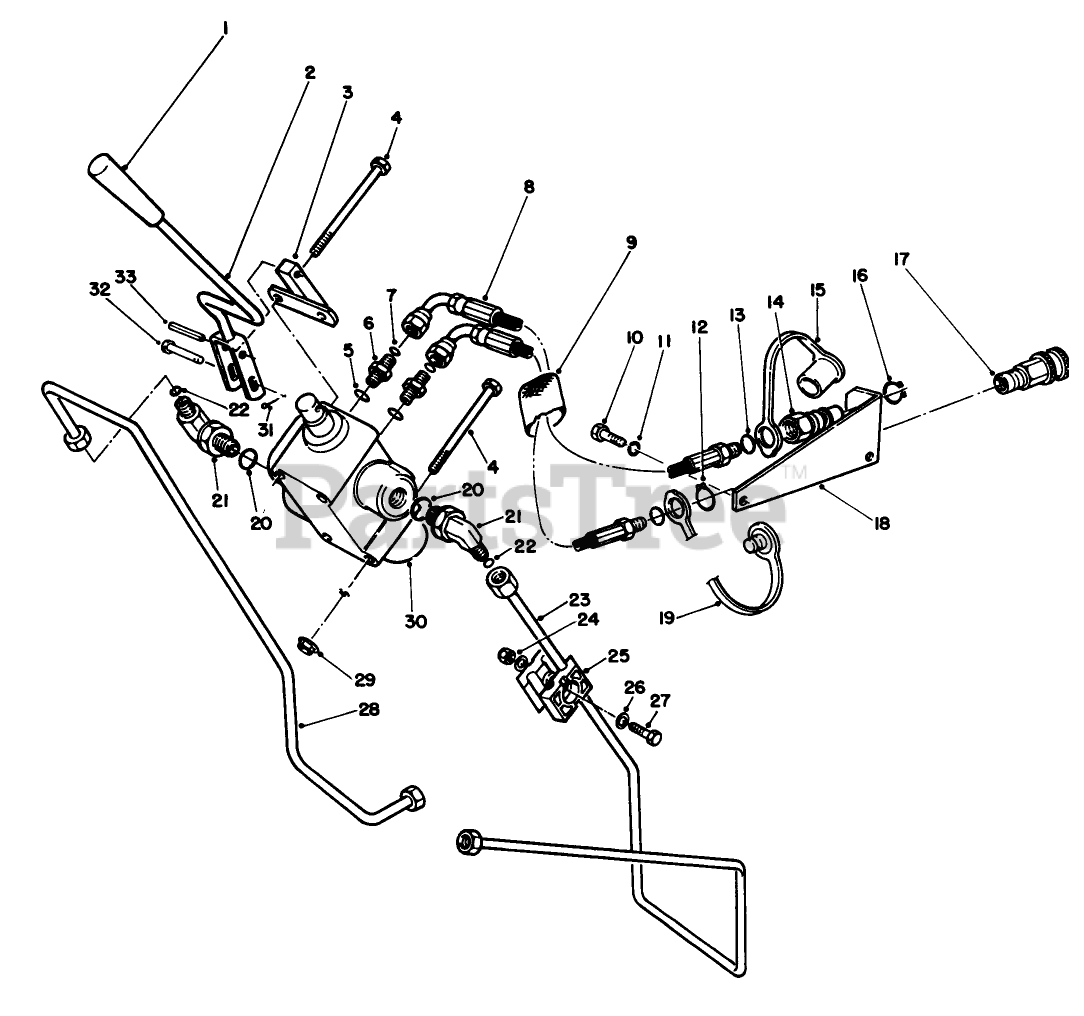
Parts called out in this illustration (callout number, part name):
1	KNOB-CONTROL
2	VALVE LEVER ASM, WELDED
3	LEVER-PIVOT
4	SCREW-HH
5	O-RING
6	FITTING-STRAIGHT
7	O-RING
8	HYDRAULIC HOSE ASM
9	SLEEVE-PROTECTIVE
10	SCREW-HH
11	WASHER-LOCK
12	RING-SNAP
13	O-RING
14	NIPPLE-DISCONNECT, QUICK
15	CAP-DUST
16	RING-RETAINING
17	COUPLER-DISCONNECT, QUICK
18	QUICK COUPLER BRKT R
19	PLUG-DUST
20	O-RING
21	FITTING-ELBOW, 90 DEG
22	O-RING
23	LINE-HYD (PRESSURE)
24	NUT-HEX
25	CLAMP-TUBE
26	WASHER-FLAT
27	SCREW-HH
28	HYD TUBE ASM
29	NUT-HF
30	HYD CONTROL VALVE ASM
31	PIN-COTTER
32	PIN-CLEVIS
33	PIN-SPRING
